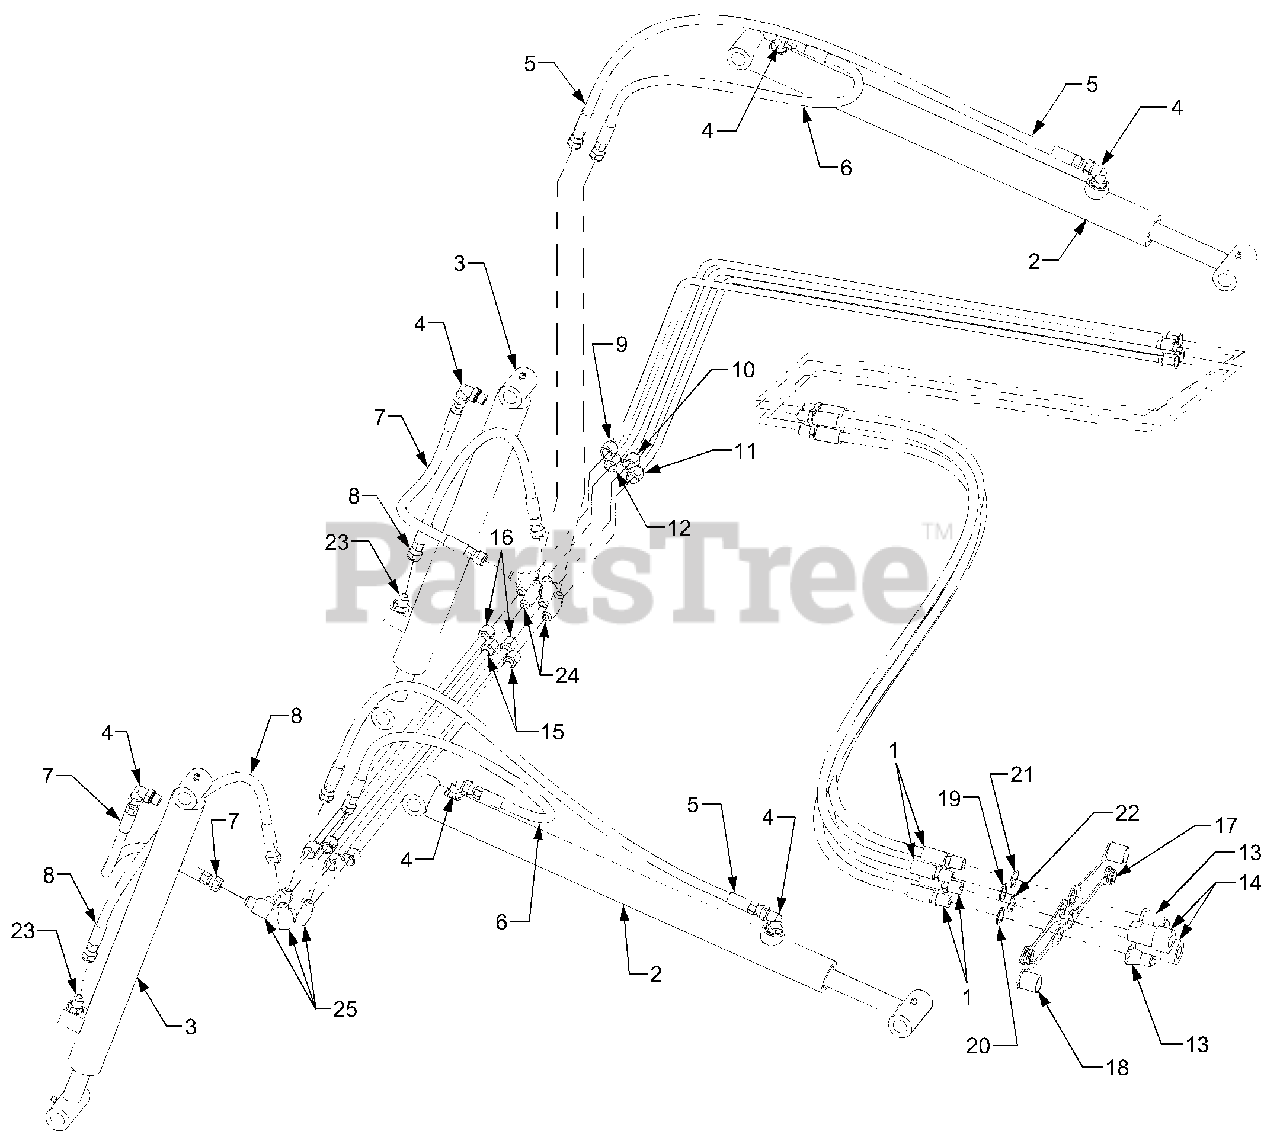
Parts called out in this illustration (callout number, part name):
1	Hose, Hydraulic, 3/8 ID
2	Cylinder, Loader Boom
3	Cylinder, Loader Bucket
4	Fitting, 90 Degree Orb
5	Hose, Hydraulic, 3/8 ID
6	Hose, Hydraulic, 3/8 ID
7	Hose, Hydraulic, 3/8 ID
8	Hose, Hydraulic, 3/8 ID
9	Tube, Hydraulic
10	Tube, Hydraulic
11	Tube, Hydraulic
12	Tube, Hydraulic
13	Coupling, Hydraulic, 3/8-18 Male
14	Coupling, Hydraulic, 3/8-18 Female
15	Tube, Hydraulic
16	Tube, Hydraulic
17	Plug, Hydraulic Coupler, Male
18	Plug, Hydraulic Coupler, Female
19	Washer, Indicator, Red
20	Washer, Indicator, Yellow
21	Washer, Indicator, Green
22	Washer, Indicator, Blue
23	Fitting, Straight
24	Fitting, Union Tee
25	Fitting, Union Tee
